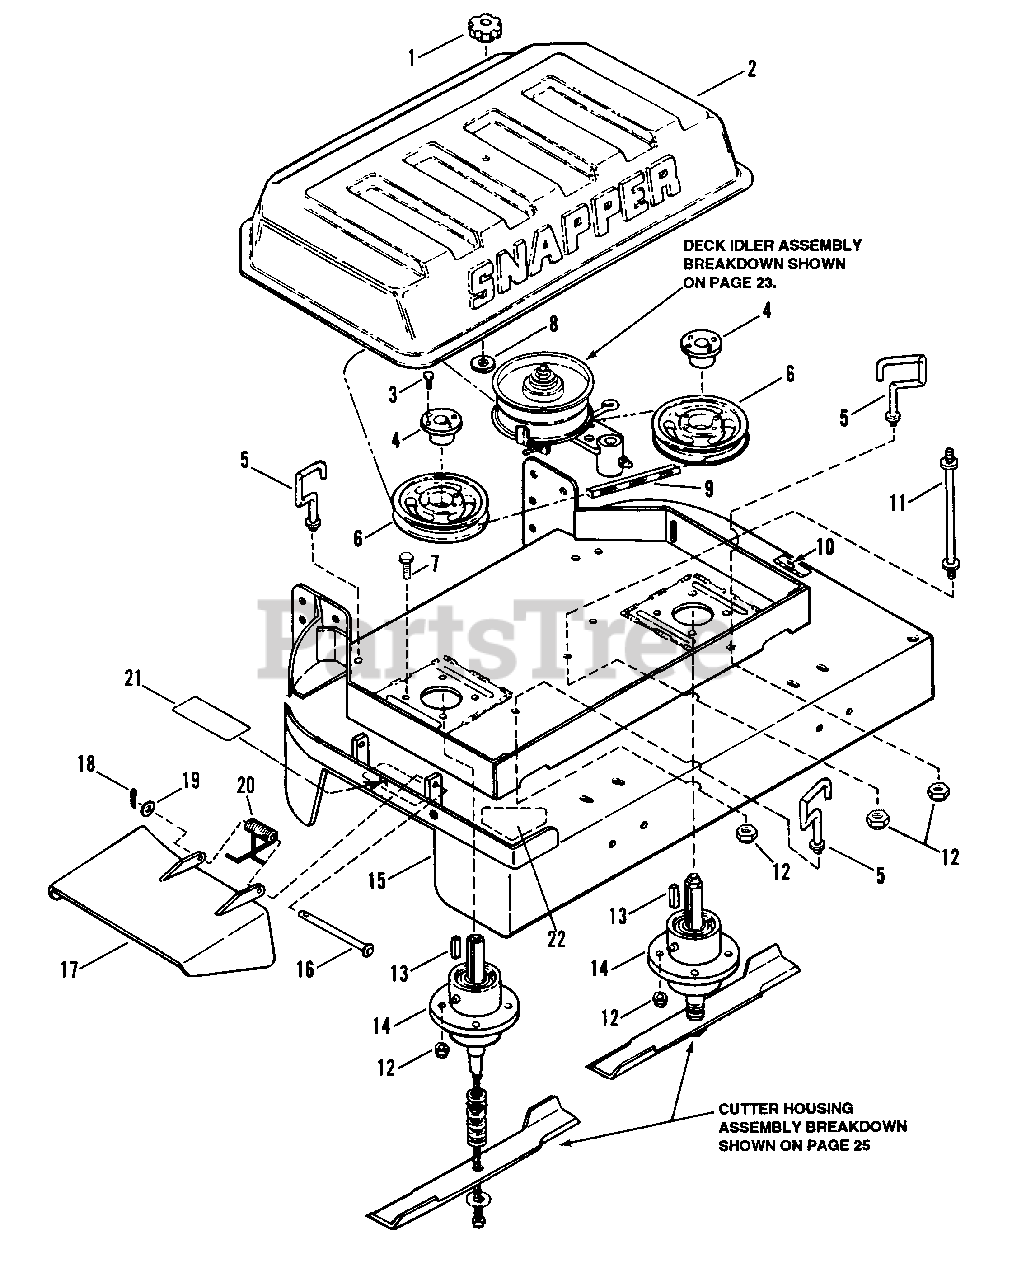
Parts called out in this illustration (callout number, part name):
1	KNOB, Hood
3	BOLT, 1/4-20 x 7/8" Hex Head Cap
4	BUSHING, Taperlock
5	GUIDE, Belt
6	PULLEY, Cutter Blade Drive
7	BOLT, 3/8-16 X 1-1/4" GD5 CZ
8	WASHER,13/32" I.D., 1 1/2" O.D.
9	BELT, 36" Deck
10	DECAL, Caution
11	STUD, Hood Mount
12	NUT, 3/8-16 HEX NYLON LOCK
13	KEY, Spindle, 1/4 x 1/4 x 2 1/2"
14	ASSEMBLY, Cutter Housing
15	WELDMENT, 36" Deck
16	ROD, Chute Pivot
17	DEFLECTOR, 36" Chute
18	PIN, 3/32 x 1" Cotter
19	WASHER, 5/16 Flat
20	SPRING, Chute
21	DECAL, Caution
22	DECAL, Danger
